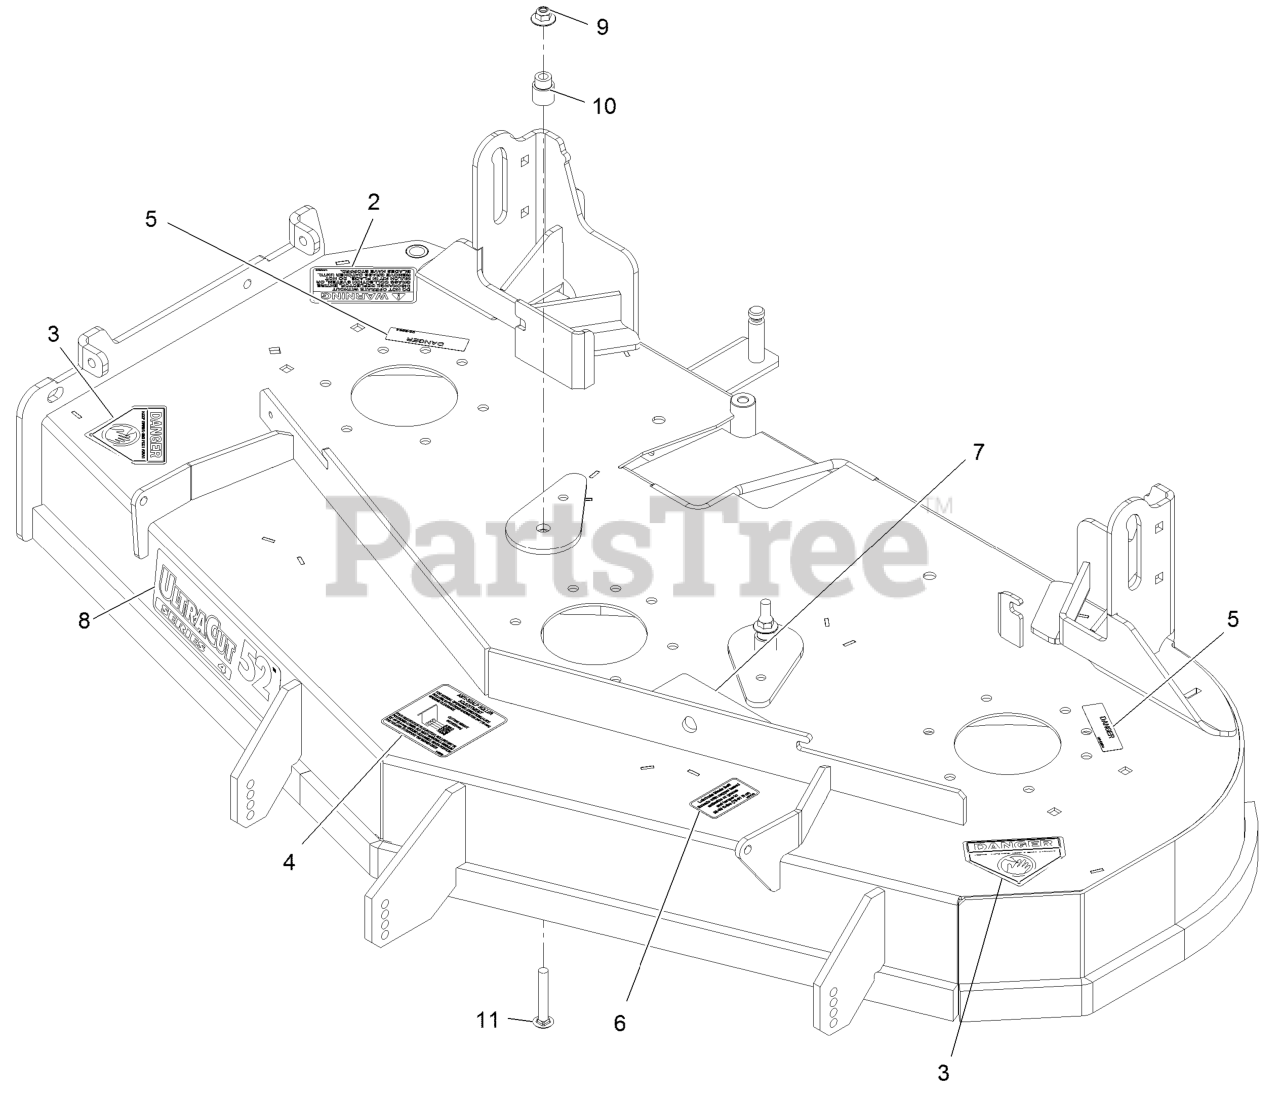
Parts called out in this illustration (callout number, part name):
2	DECAL-WARNING, DISCHARGE
3	DECAL-DANGER
4	DECAL,ANTISCALP
5	DECAL-COVER, MISSING
6	DECAL,BOLT TORQUE
7	DECAL,BELT ROUTING
8	DECAL,ULTRACUT 52 SERIES
9	Nut-Nyloc 3/8-16 Flg
10	BUSHING-IDLER
11	SCREW-CARR
